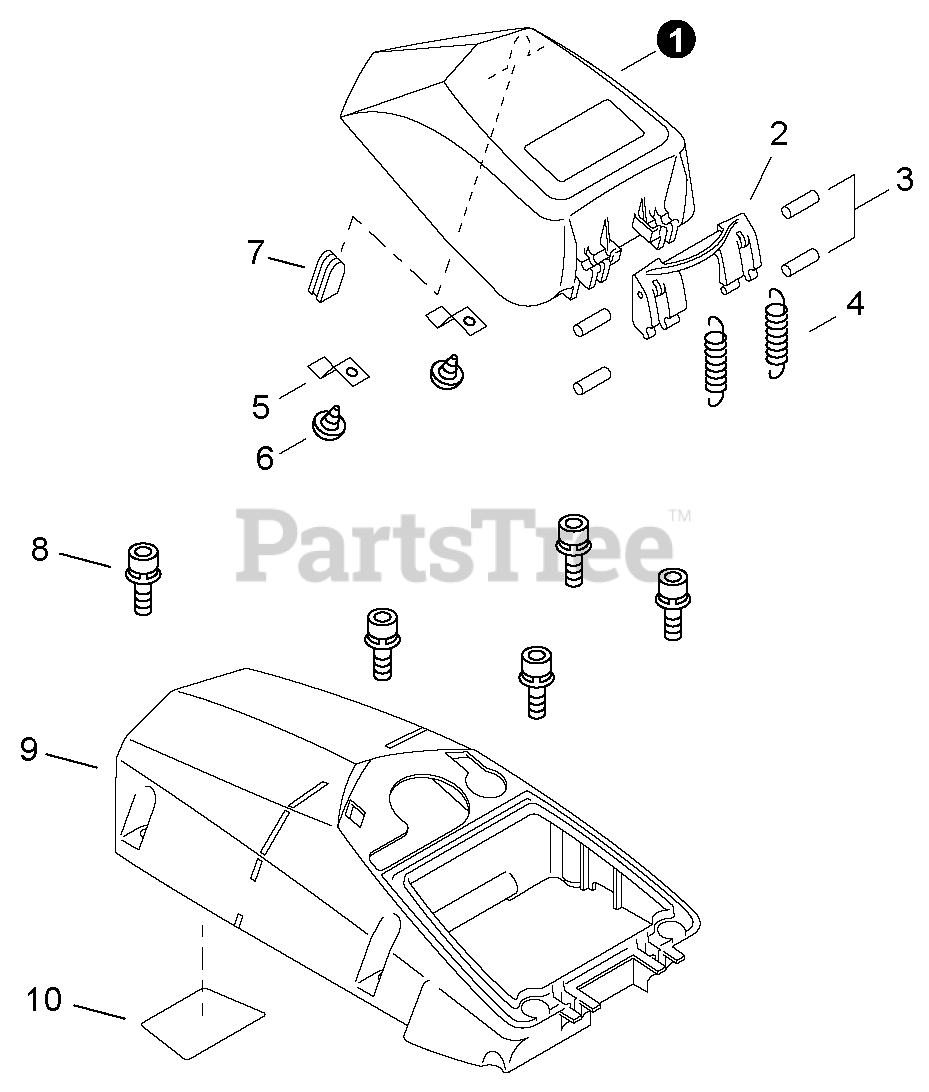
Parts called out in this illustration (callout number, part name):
1	COVER, AIR FILTER
2	LATCH, FILTER COVER
3	PIN - 3X12
5	SPRING, FLAT
6	SCREW - 4X10
8	SCREW - 5X20
9	COVER, ENGINE
10	DEFLECTOR, HEAT
